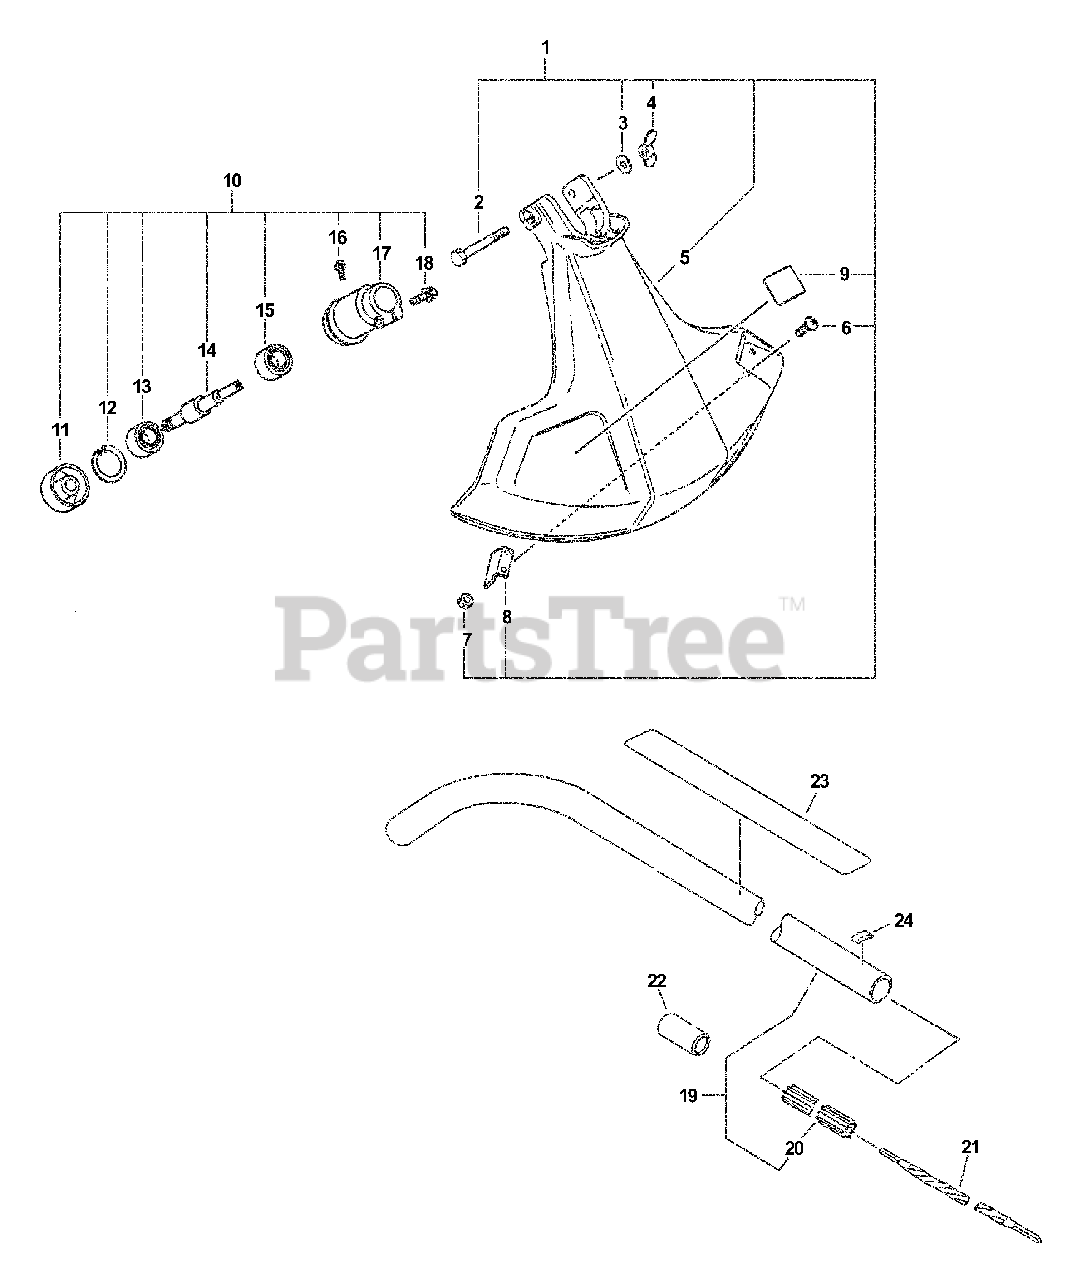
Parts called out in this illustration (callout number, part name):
1	DEBRIS SHIELD KIT
2	BOLT - 1/4-20 X 2"
3	WASHER - 1/4"
4	WINGNUT - 1/4-20
5	SHIELD, DEBRIS - PLASTIC
6	SCREW - 5X16
8	KNIFE, TRIMMER LINE
9	LABEL - CAUTION
10	GEAR CASE ASSY
11	ADAPTOR, BLADE - UPPER
12	RING, RETAINING - 30
13	BEARING, BALL - 6201
14	GEAR - SHAFT
15	BEARING, BALL - 6200
16	SCREW - 4X10
17	CASE, GEAR
18	BOLT - 5X25
19	MAIN PIPE ASSY
20	LINER - FLEXIBLE
21	DRIVESHAFT - FLEXIBLE
22	CUSHION
23	LABEL - CAUTION
24	LABEL - CAUTION
